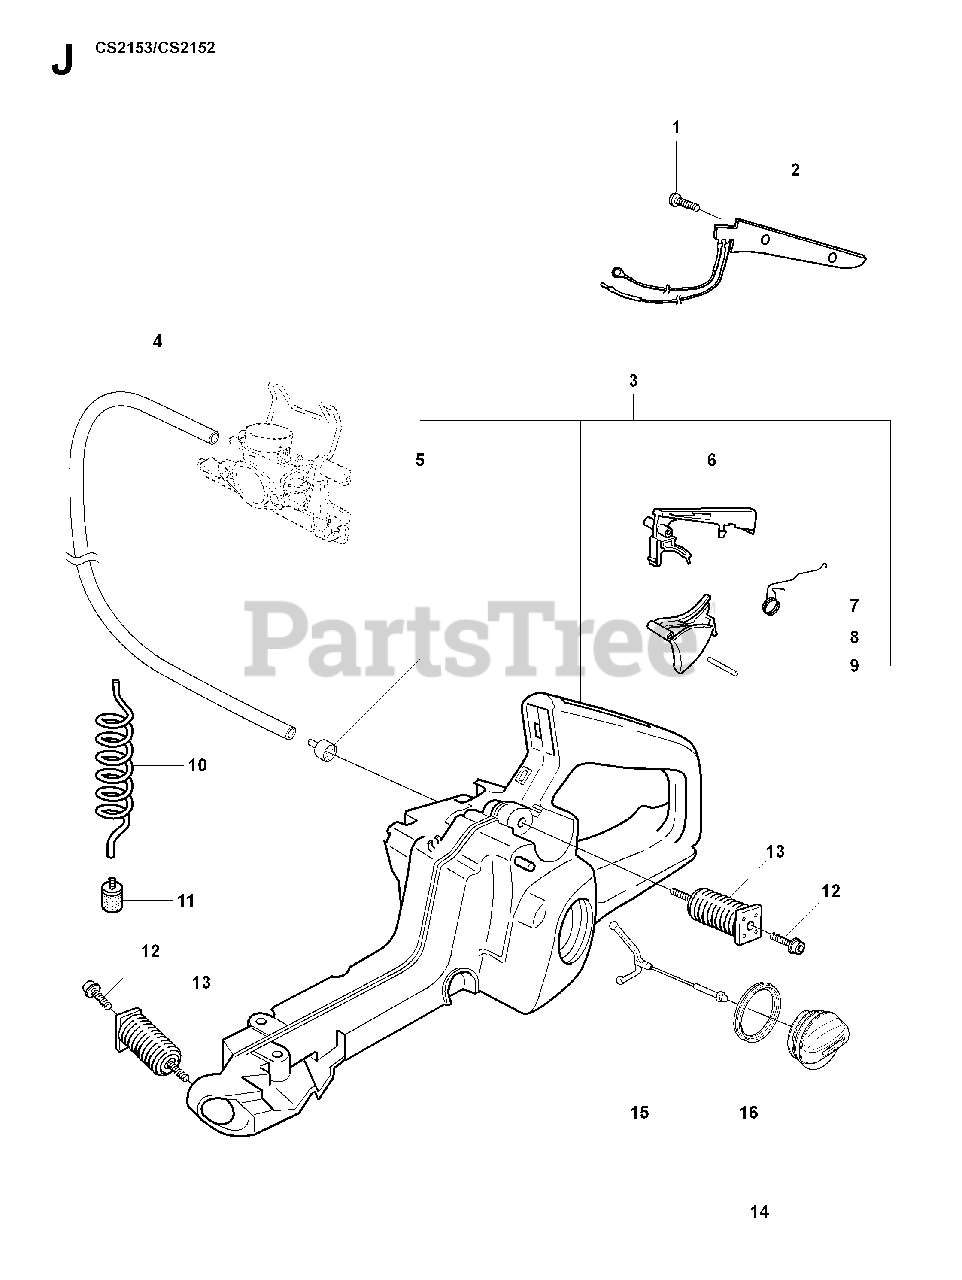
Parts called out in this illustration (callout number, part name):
2	HANDLE CIRCUIT
3	TANK UNIT
4	FUEL HOSE
5	FUEL TANK VENT
6	THROTTLE LOCK
8	THROTTLE TRIGGER
10	FUEL HOSE
11	FUEL FILTER
13	VIBRATION ABSORBER
14	TANK CAP
16	SEALING
